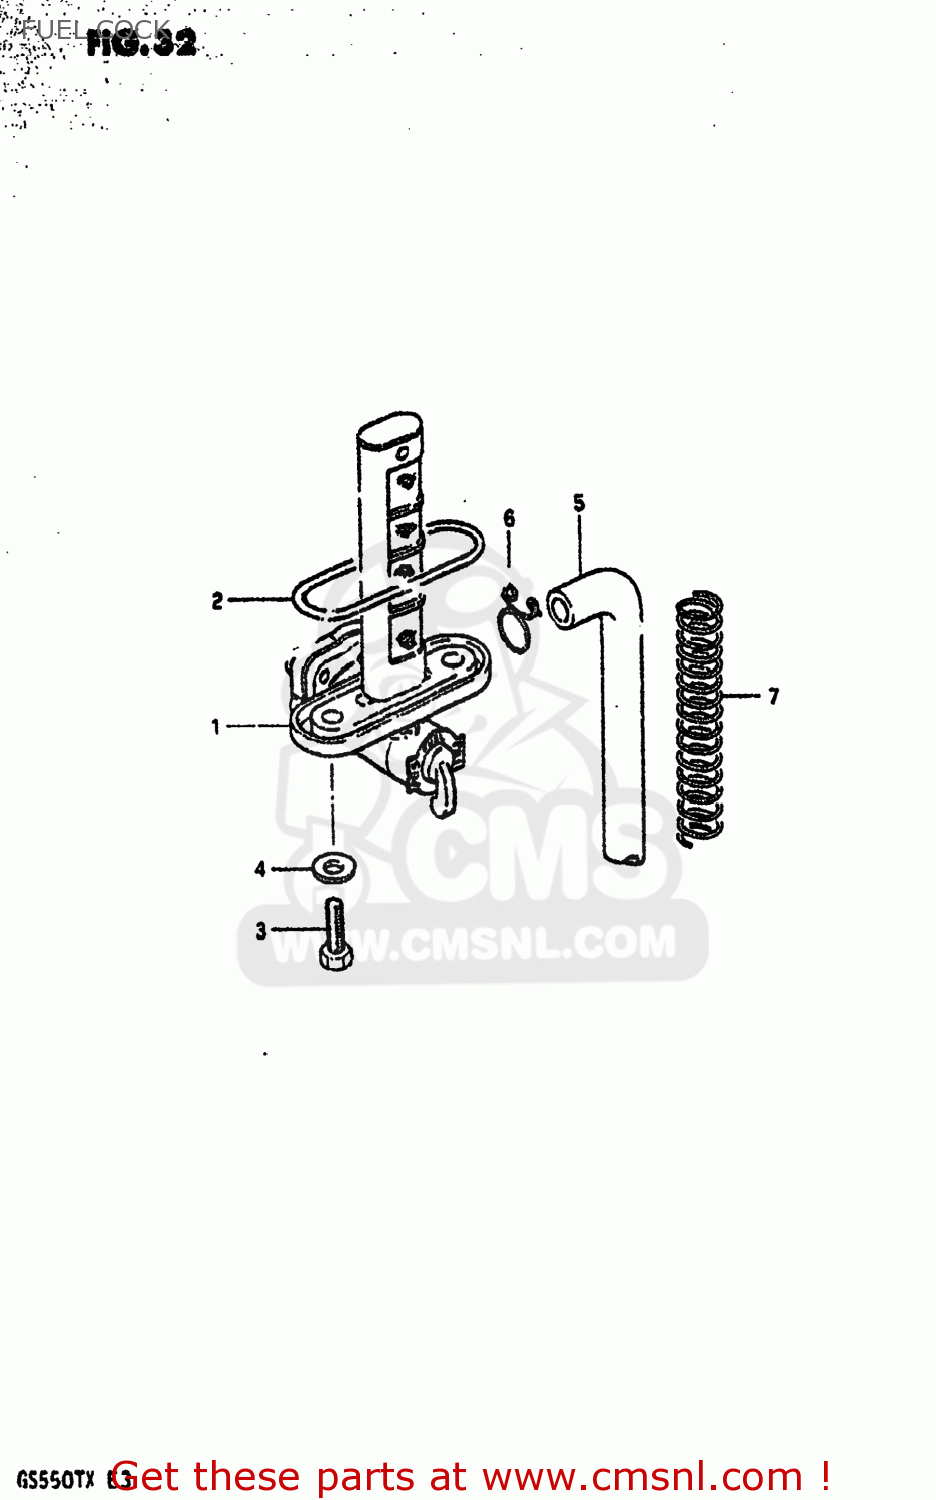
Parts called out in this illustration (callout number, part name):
1	COCK ASSEMBLY,FUEL
2	O RING
3	BOLT(6X20)
4	GASKET
5	HOSE
6	CLIP
7	SPRING
